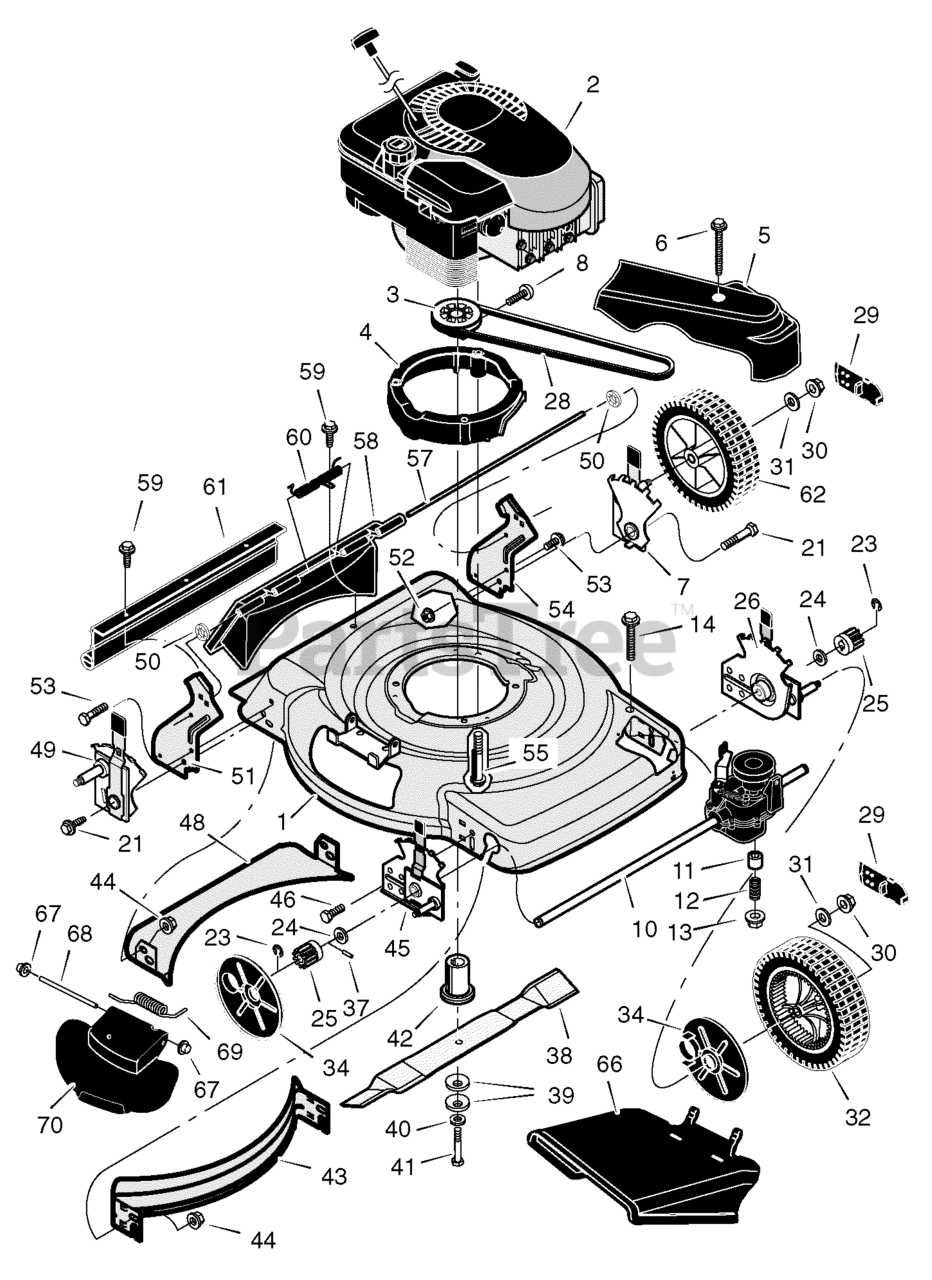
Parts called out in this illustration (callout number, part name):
1	Housing
2	Engine *
3	Pulley, Drive
4	Spacer, Engine
5	Cover, Belt (Black)
5	Cover, Belt (Gray)
7	Adjuster, Left Rear Height
10	Transmission *
11	Spacer
12	Spring, Compression
14	Bolt
23	E-Ring
24	Washer
25	Gear, Pinion
26	Adjuster, Left Front Height
29	Cap, Hub
30	Nut, Flange
31	Washer
32	Wheel & Tire, Front
34	Cover, Dust
37	Pin, Drive
39	Washer, Belleville
40	Washer
42	Adapter, Blade
43	Baffle, Front
44	Nut, Flange
45	Adjuster, Right Front Height
46	Bolt
48	Baffle, Rear
49	Adjuster, Right Rear Height
50	Retainer, Push
51	Bracket, Right Handle
52	Nut, Flange
53	Bolt
54	Bracket, Left Handle
55	Bolt, Engine
57	Rod, Pivot
58	Door, Rear (Black)
58	Door, Rear (Gray)
60	Spring
61	Guard, Rear
62	Wheel & Tire, Rear
66	Deflector, Chute (Black)
66	Deflector, Chute (Gray)
67	Push On Cap
68	Rod, Pivot
69	Spring, Torsion
70	Cover, Mulch (Black)
70	Cover, Mulch (Gray)
